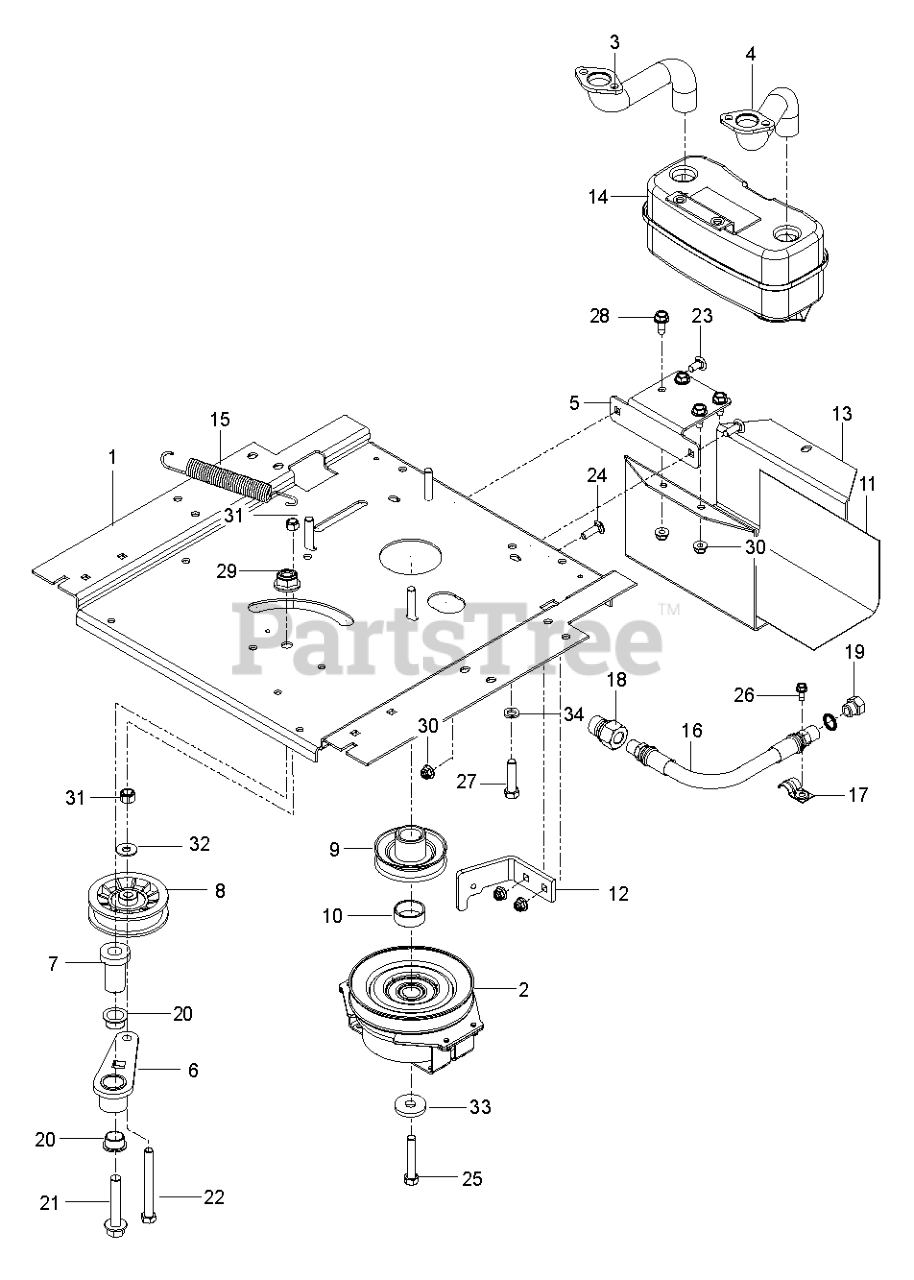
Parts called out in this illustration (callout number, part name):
1	PLATE.ENGINE.PNT.23"FRAME.EDIP
2	CLUTCH.OGURA.5.0PD.GT1.5A-EH07
3	TUBE.EXHAUST.RH.FR961/FR730
4	TUBE.EXHAUST.LH.FR961/FR730
5	BRACKET MUFFLER MS431BLK
6	ARM IDLER
7	SPINDLE.IDLER
8	PULLEY, IDLER RAKE & ZTR
9	PULLEY.ENGINE
10	SPACER.SPACER.625 W/OGURA.LCC
11	HEAT SHIELD
12	CLUTCH.STOP.OGURA LCC.BLACK
13	GUARD.MUFFLER.WO.TOW.HITCHX431
14	MUFFLER ASM TWIN
15	SPRING, DECK DRIVE
16	HOSE.ASSEMBLY.OIL.DRAIN
18	ADAPTER, OIL DRAIN
19	PLUG OIL DRAIN
20	BEARING.FLANGED.PLASTIC.3/4ID
21	BOLT.FLANGE.1/2-13 X 2.75.GRD5
22	HCS 3/8-16X3-1/2 TAPBLT GR5 ZD
23	BOLT 5/16-18 X3/4 ZN/YEL GR 5
24	BOLT
25	CLUTCH BOLT7/16-20X2.5 GR524HR
26	SCR 1/4-20X5/8 HEX SELF TAP ZD
27	BOLT, HCS 3/8-16X1-3/4
28	SCREW
29	NUT, 1/2-13 HEX FLG NYLOC ZD
30	5/16-18 NYLOC FLANGE NUT
31	NUT 3/8-16 NYLOC
32	WASHER 5/16 FLAT
34	LOCKWASHER
